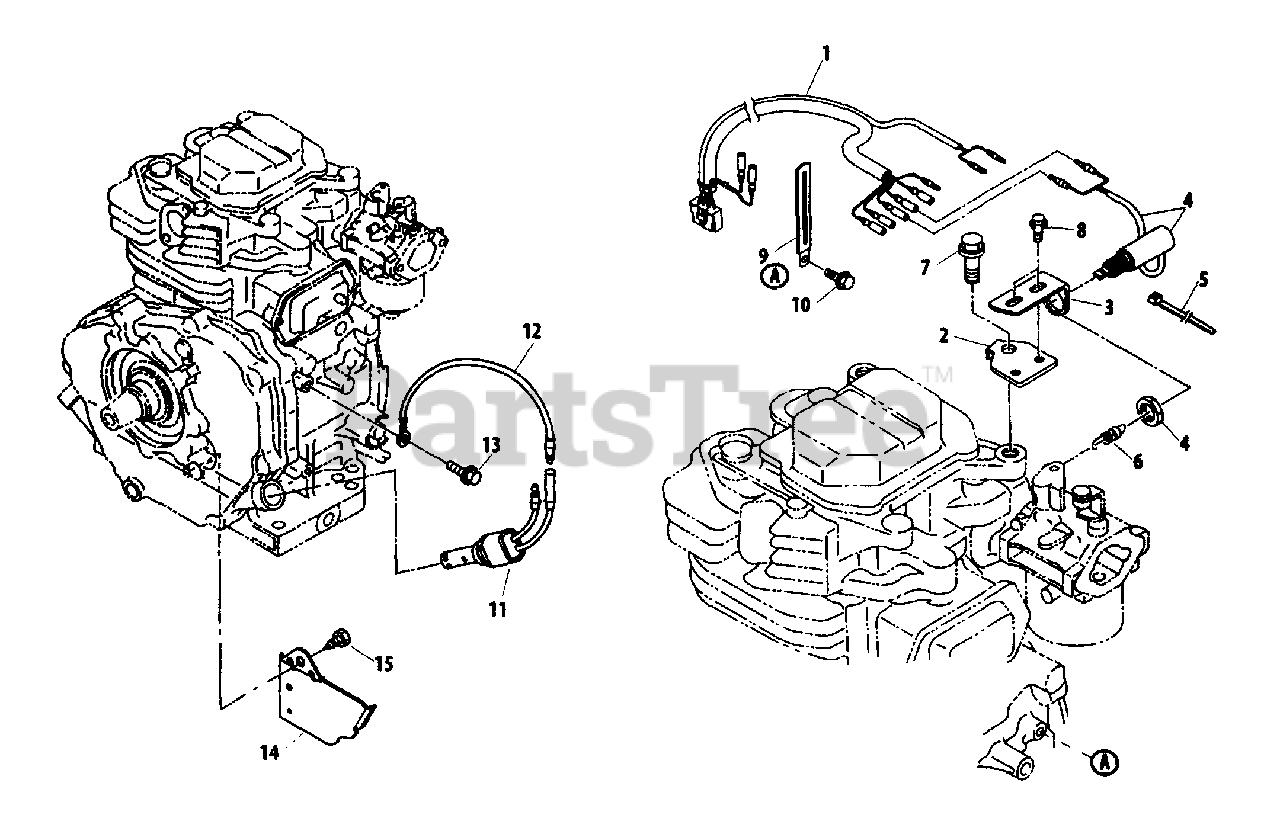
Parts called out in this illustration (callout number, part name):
1	WIRE - 19 COMPL.
2	BRACKET, SOLENOID 1
3	BRACKET, SOLENOID 2
5	BAND
6	SPRING (SOLENOID)
7	BOLT
8	BOLT
9	CLAMP
10	BOLT - FLANGE
11	OIL SENSOR, COMPL.
12	WIRE - 3 COMPL.
13	BOLT - FLANGE
14	PLATE
15	BOLT - TAPPING
